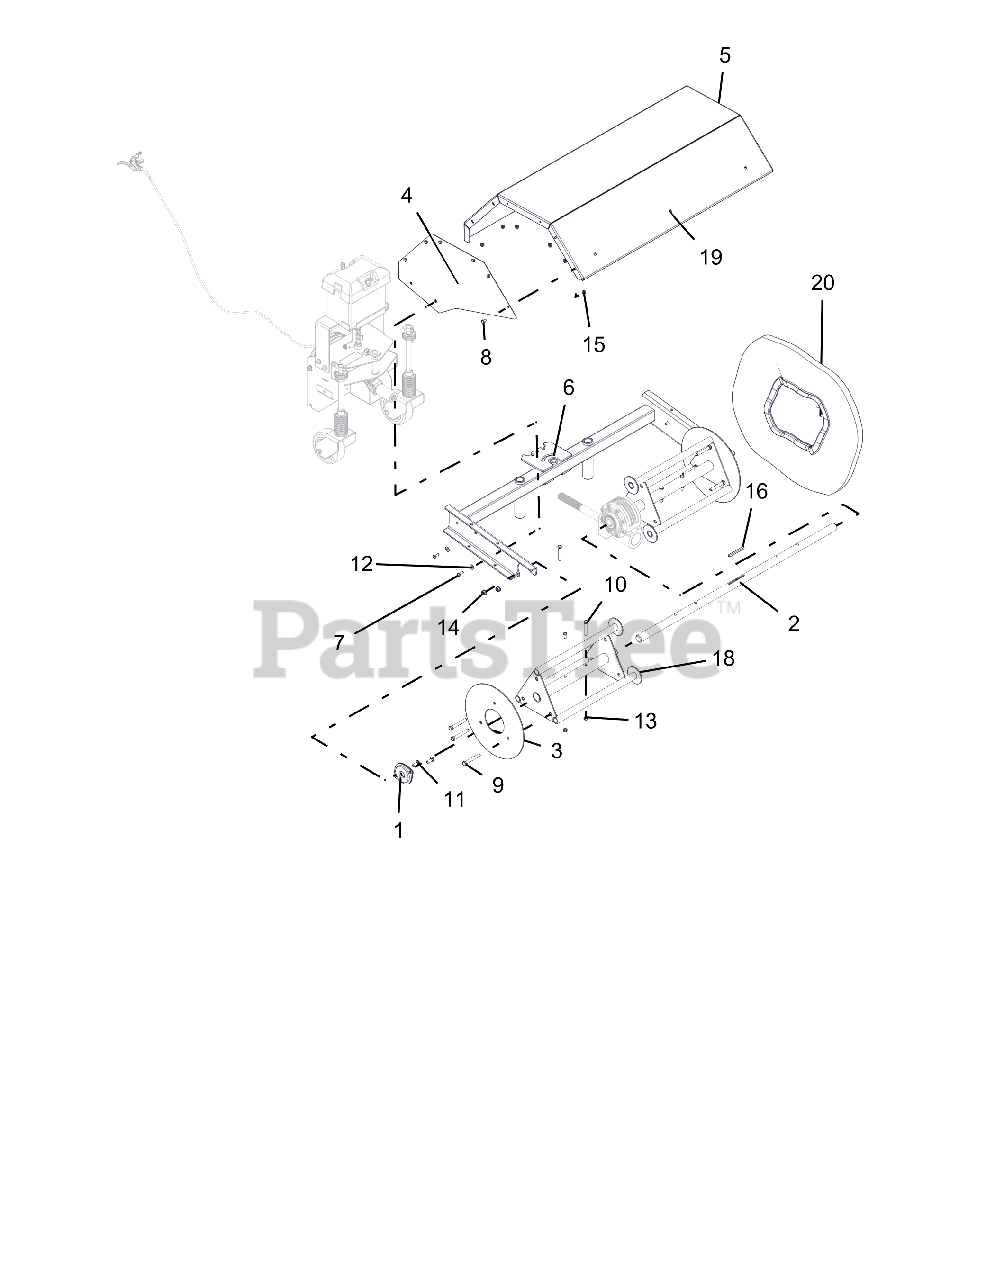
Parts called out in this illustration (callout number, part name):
1	BEARING,2 BOLT FLANGE 1-1/8 ID
2	CENTER, SHAFT
3	PLATE, END RETAINER
4	WLDT, SIDE COVER - RH
5	WLDT, SIDE COVER - LH
6	FRAME, POWER BROOM 36"
7	@BLT-HEX .25-20X.75 GR5 YWZC
8	@BLT-HEX .25-20X.50 GR5 YWZC
9	BLT-HEX .38-16X3.00 GR5 FTH YZ
10	@BLT-HEX .31-18X2.25 GR5 YWZC
11	@BLT-RDHDSQNK .38-16X1.00 G5YZ
12	@WSHR-FL-STL.312X.734X.065 YWZ
13	@NUT-LK-CTR .31-18 YWZC
14	@NUT-LK-TOP-FLG .38-16 YWZC
15	@NUT-LK-TOP-FLG .25-20 YWZC
16	KEY .25 X .25 X 3IN
18	PB36 DRIVE CORE SERVICE KIT
19	COVER, TOP - 36" BRUSH W/DECAL
20	KIT, BRISTLE - SET OF 18
